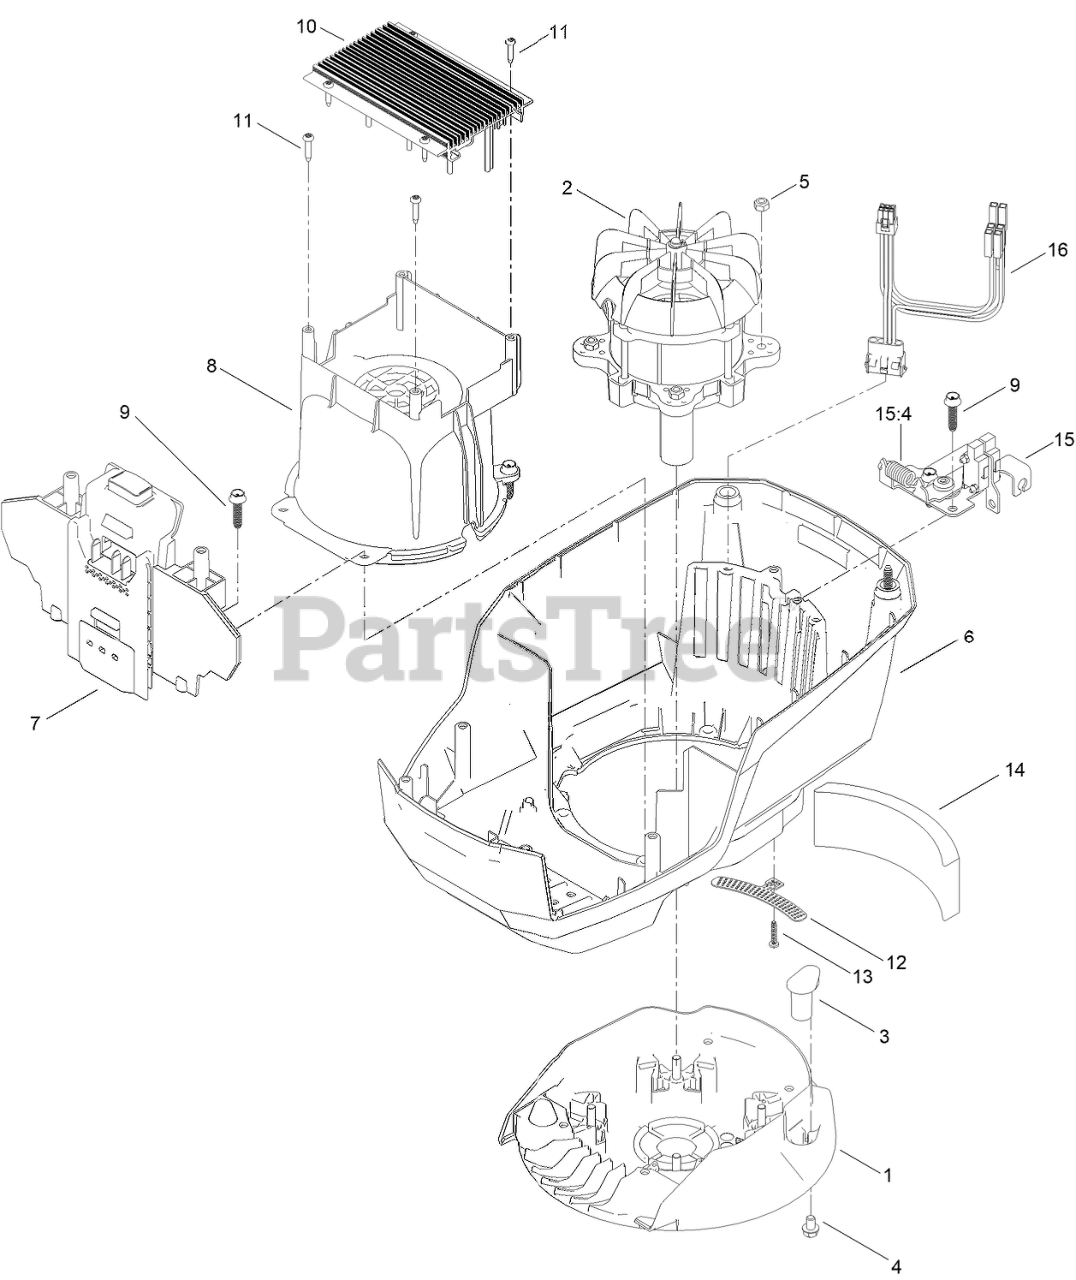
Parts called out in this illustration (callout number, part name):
1	SHROUD-UPPER
1	BASE-MOUNT, MOTOR
2	MAGNET
2	MOTOR-2KW
3	INSERT-MOUNT, Motor
3	SCREW-FLANGE, PLASTIC
5	NUT-LOCK
5	SPRING-LH
6	SHROUD-LOWER
6	SPRING-RH
7	SCREW-PPH
7	BATTERY RECIEVER ASM
8	SHROUD-MOTOR
8	DECAL-HOOD, TOP
9	DECAL-HOOD, FRONT
9	SCREW-FLANGE, PLASTIC
10	CONTROLLER-MOTOR [2 SPD]
12	BRACKET-FOAM
13	SCREW-PLASTIC, PPH
15	BAIL SWITCH ASM
15:4	SPRING-EXTENSION
16	HARNESS-WIRE
